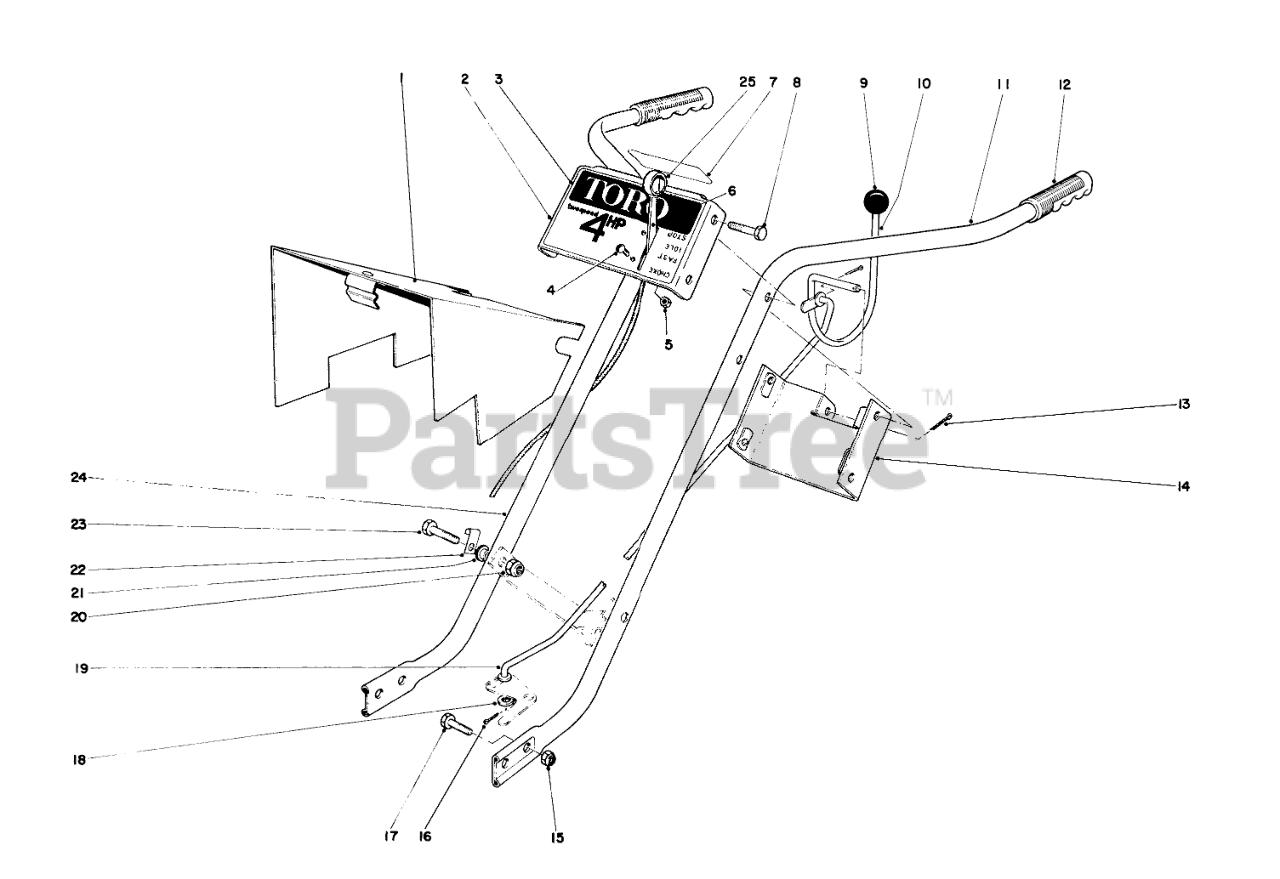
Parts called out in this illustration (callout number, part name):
1	Pulley Cover
2	Control Plate
3	Decal, Control
4	SCREW-PPH
5	NUT-KEPS
6	Throttle Control
7	Decal Clutch
8	SCREW-HH
9	KNOB-CONTROL
10	Clutch Control
11	Handle L.H.
12	Handle Grip
13	PIN-COTTER
14	Handle Brace
15	NUT-LOCK, CONE
16	PIN-COTTER
17	SCREW-HH
18	WASHER-FLAT
19	Clutch Rod
20	NUT-LOCK, CONE
21	Spacer
23	SCREW-HH
24	Handle R.H.
